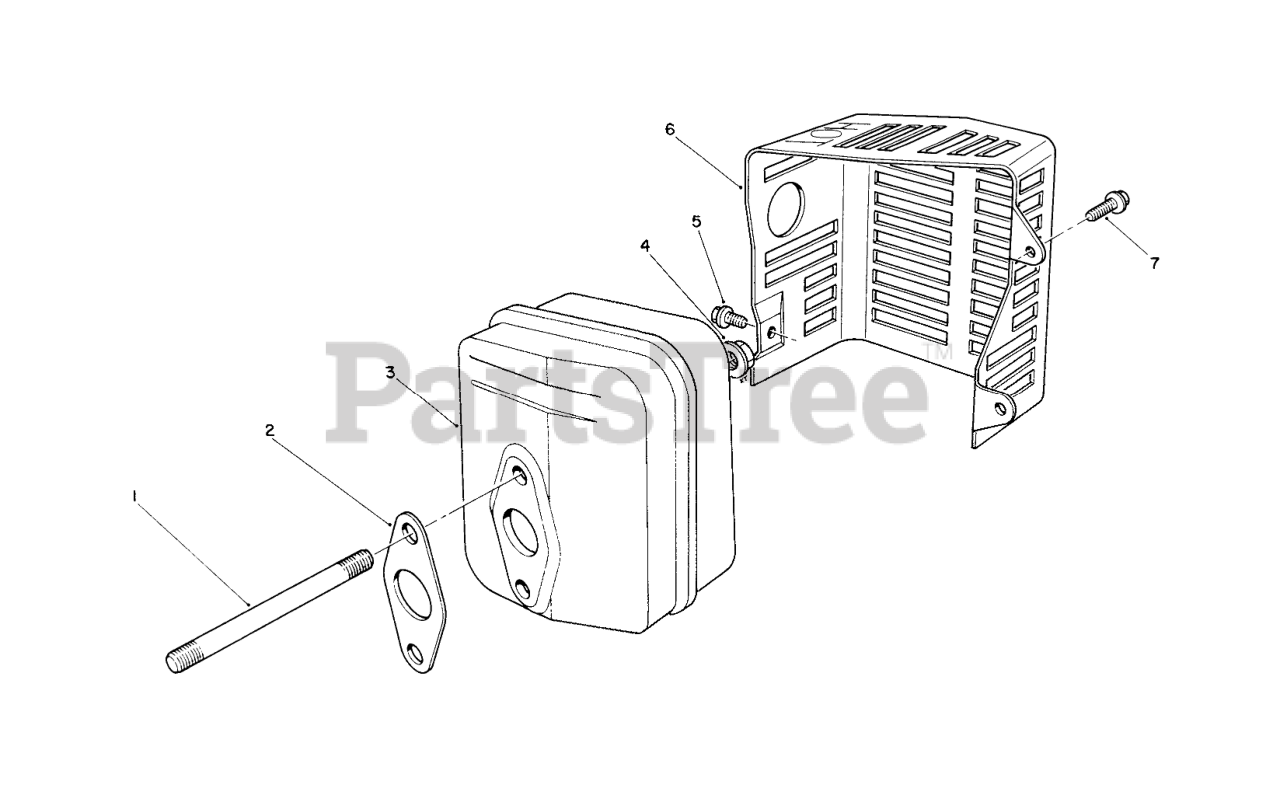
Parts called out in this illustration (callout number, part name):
2	GASKET
3	MUFFLER
5	SCREW
6	COVER
